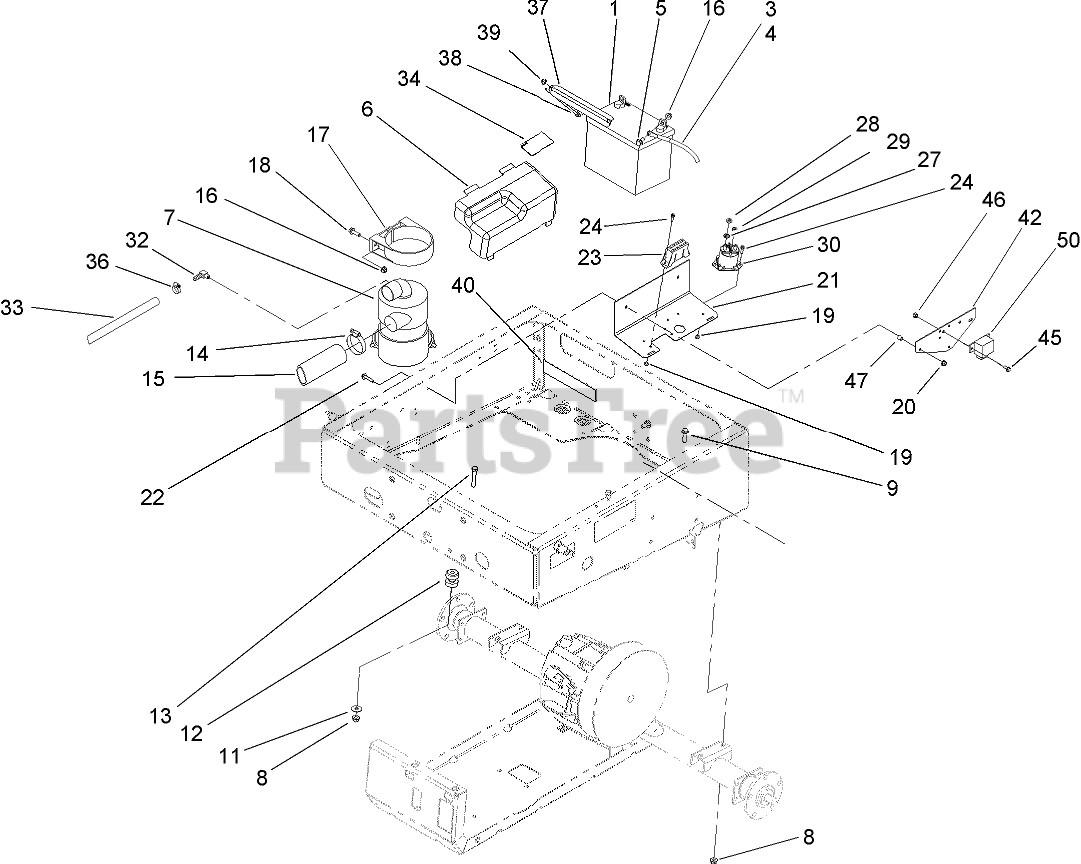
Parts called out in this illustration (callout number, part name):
1	BATTERY-DRY
3	CABLE-NEGATIVE
4	CABLE-POSITIVE
5	SCREW-HHF
6	COVER-ELECTRICAL
7	AIR CLEANER ASM
8	NUT-HF, NI
9	SCREW-HHF
11	WASHER-FLAT
12	MOUNT-ISO
13	SCREW-HH
14	CLAMP-HOSE
15	HOSE-INTAKE
16	NUT-HF, NI
17	BRACKET-MOUNTING
18	SCREW-HHF
19	NUT-LOCK, NI
20	NUT-HHF
21	MOUNT-COMPONENT
22	SCREW-HHF
23	HARNESS-WIRE, MAIN
24	SCREW-HWH
27	WASHER-LOCK
28	NUT-JAM
29	NUT-KEPS
30	SOLENOID
32	FITTING-90 DEG
33	HOSE-BREATHER
34	DECAL-INFORMATION
36	CLAMP-HOSE
37	CLAMP-BATTERY
38	HOOK-RETAIN, BATTERY
39	NUT-HF
40	Pad-Battery
42	BRACKET-IGNITION
45	SCREW-HHF
46	NUT-LOCK, NI
47	SPACER
50	RELAY
